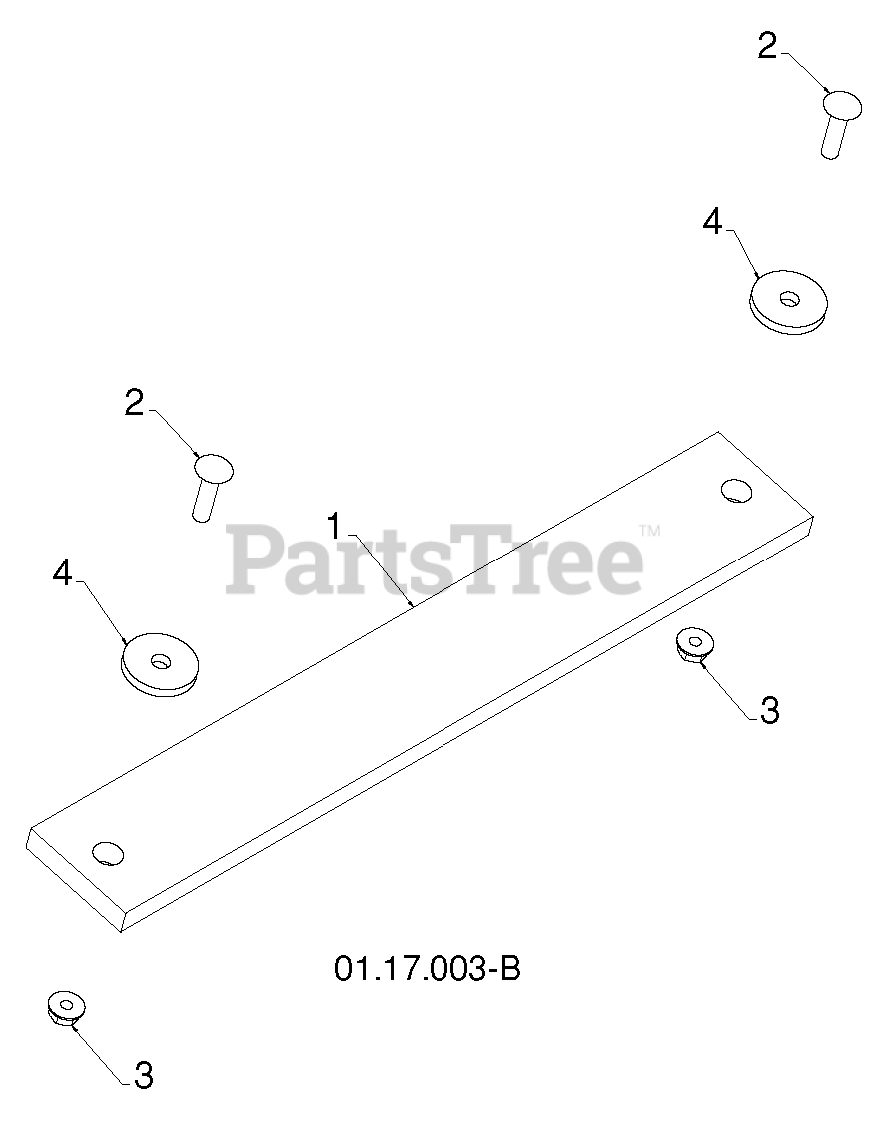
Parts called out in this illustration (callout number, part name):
1	WEIGHT AUGER HOUSING 30
2	BOLT.CARRIAGE.5/16-18
3	NUT.LOCK.5/16-18
4	WASHER.FLAT.34X1.38X22
